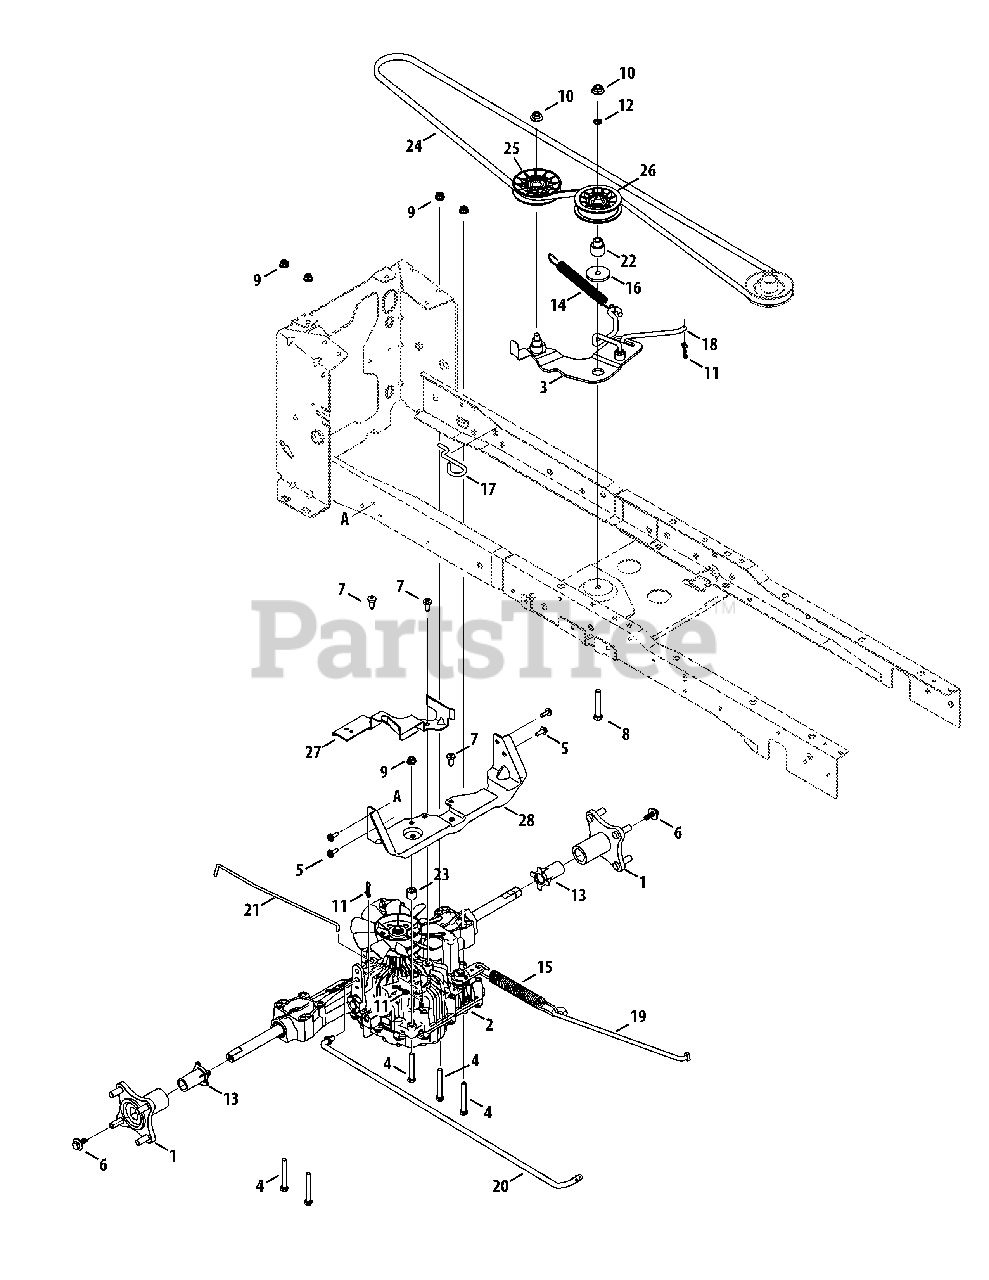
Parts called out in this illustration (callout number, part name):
1	Hub Assembly, Wheel
2	Transmission, Tuff Torq K46
3	Idler bracket Assembly
4	Hex Screw, 5/16-18, 2.50, Gr5, Std
5	Screw, M6-1 x .625
6	Screw, 5/16-24 x .850
7	Screw, Self-tapping, 5/16-18, 0.750
8	Hex Screw, 3/8-16, 2.25, Gr5
9	Nut, Flange Lock, 5/16-18, Nylon
10	Flange Lock Nut, 3/8-16
11	Pin, Cotter, Bow-Tie 72
12	Speed Nut
13	Sleeve, .765 ID x 1.575
14	Spring, Extension, .700 Dia x 8.41
15	Spring, Extension, .90 Dia x 8.14
16	Shoulder Spacer, .884 x .190
17	Deck Spring Rod
18	Idler Link
19	Rod, Brake, Tuff Torq
20	Rod, Control, Tuff Torq
21	Rod, Transmission, Bypass
22	Shoulder Spacer
23	Spacer, .34 x .75 x .63
24	Belt, V-Type
25	Idler Pulley, 3.56 OD
26	Idler Pulley, 3.00 OD
27	Belt Keeper Bracket
28	Transmission Bracket
